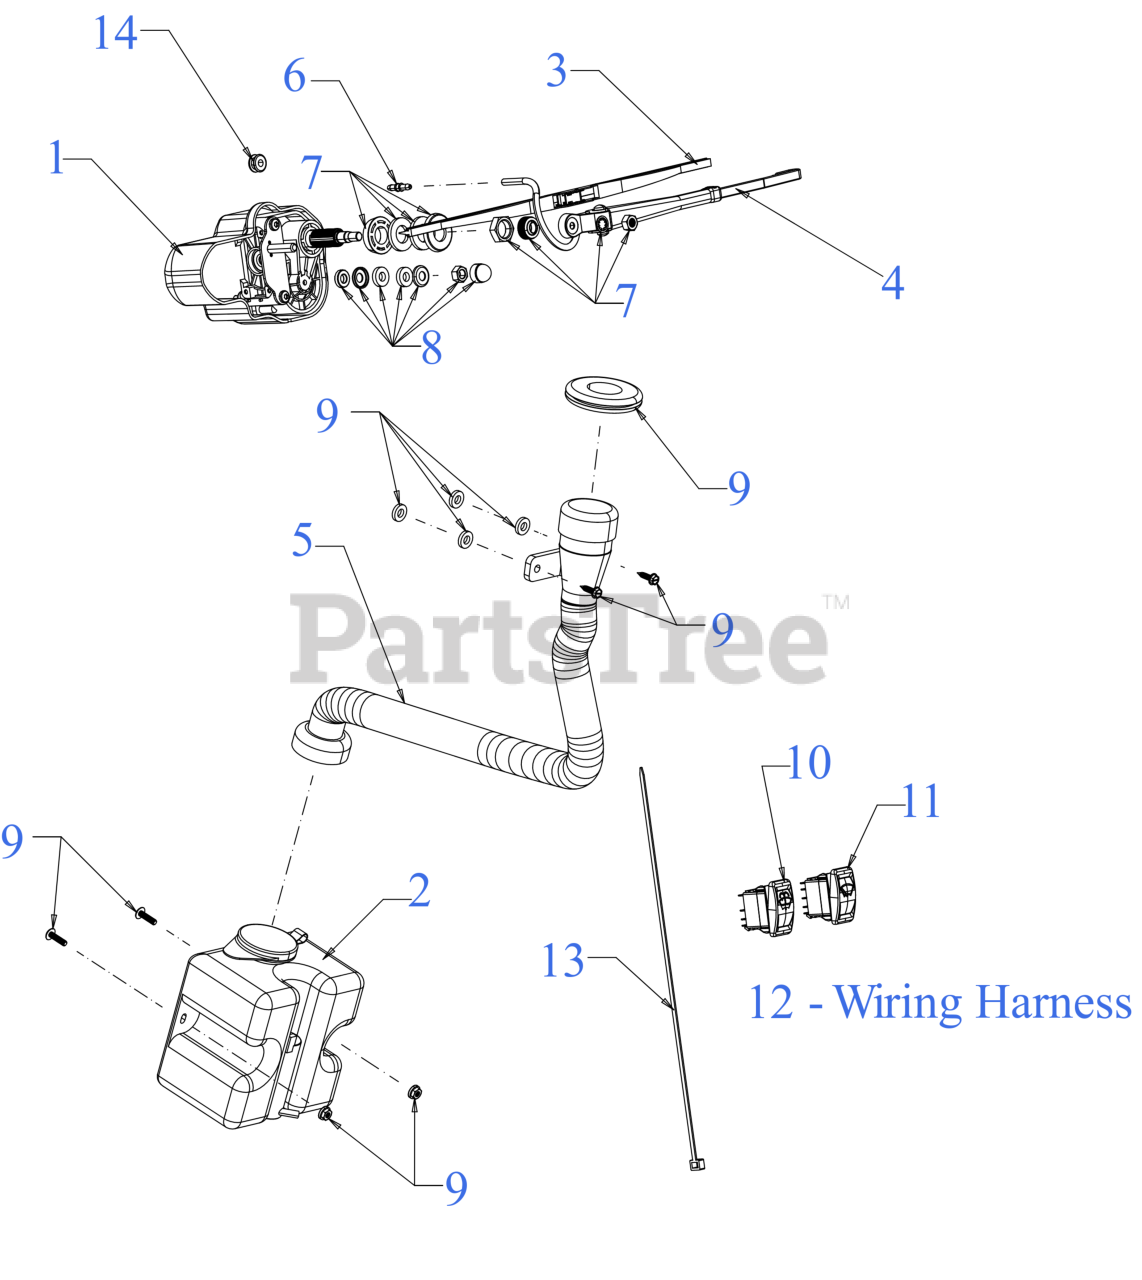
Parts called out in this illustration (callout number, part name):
1	WINDSHIELD WIPER MOTOR
2	WIPER FLUID TANK (1.2L)
3	WIPER BLADE (400MM)
4	WIPER ARM (290MM)
5	WIPER FLUID REMOTE FILLER
6	WIPER FLUID CHECK VALVE
7	WIPER SPINDLE HARDWARE KIT
8	WIPER STUD HARDWARE KIT
9	TANK HARDWARE KIT
10	FLUID PUMP DASH SWITCH
11	WIPER MOTOR DASH SWITCH
12	WIPER WIRE HARNESS
13	TIE:CBL:14.5" LONG
14	RUBBER GROMMET (.25 ID x .436 OD)
